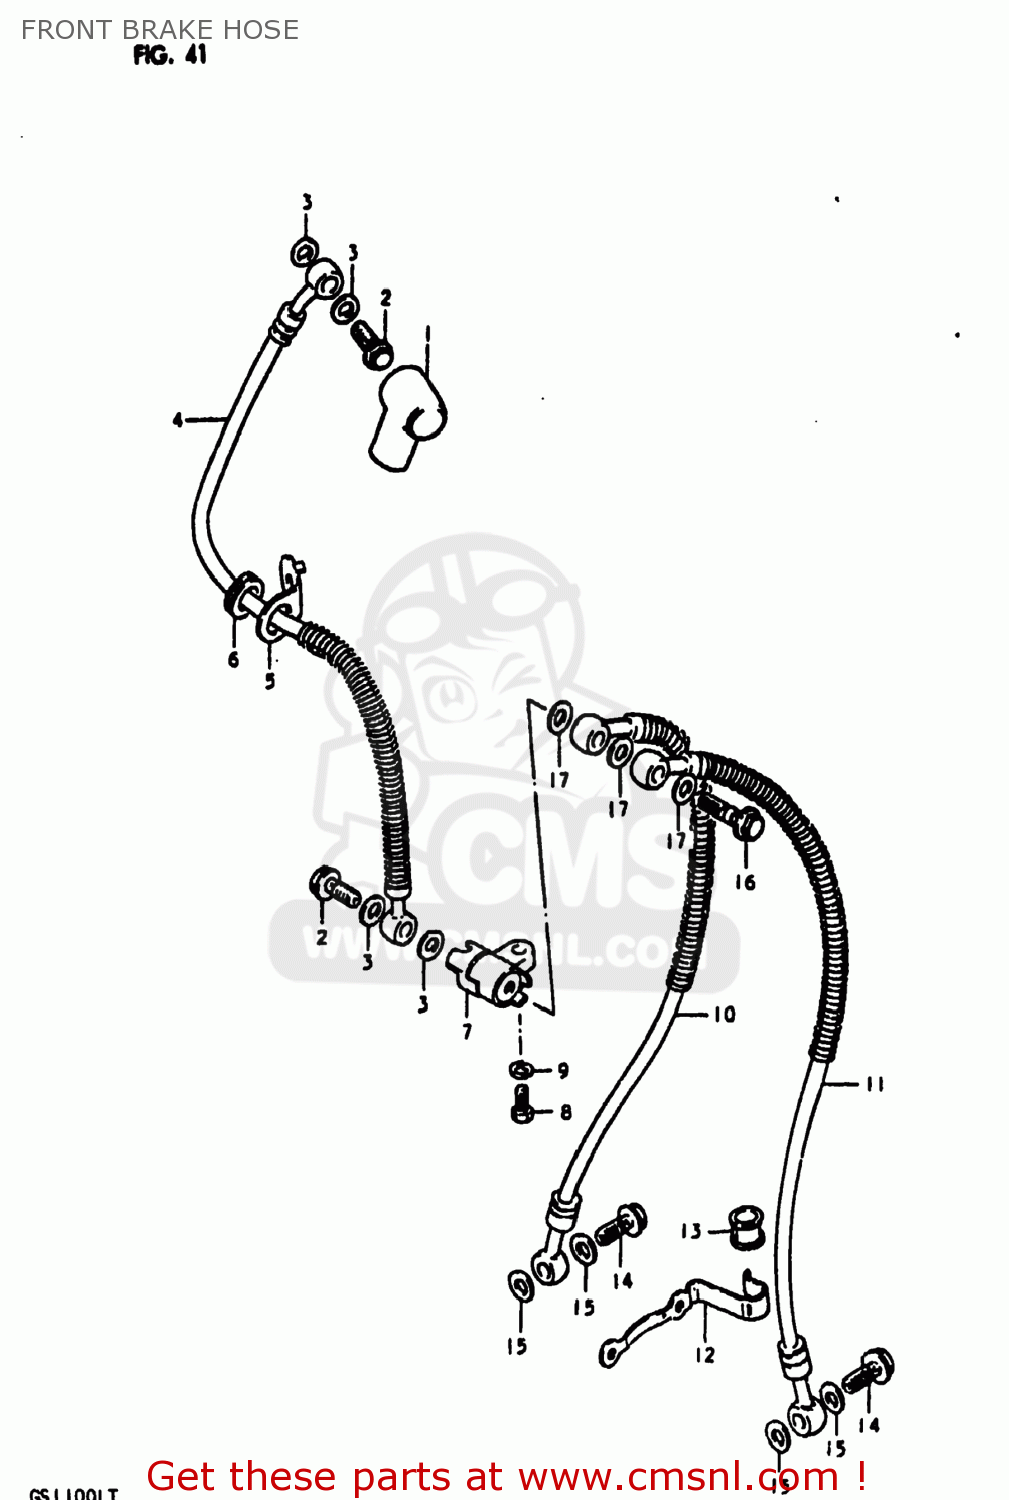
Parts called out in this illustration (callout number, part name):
1	BOOT,MASTER CYLINDER
2	BOLT,UNION
3	WASHER
4	HOSE,FRONT BRAKE NO.1
5	GUIDE,BRAKE HOSE
6	GROMMET
7	JOINT,BRAKE HOSE
8	BOLT
9	LOCK WASHER
10	HOSE,FR BRAKE NO.2,L
11	HOSE,FR BRAKE NO.2,L
12	GUIDE,BRAKE HOSE NO.2
13	BUSH,BRAKE HOSE GUIDE,NO.2
14	BOLT,UNION
15	WASHER
16	BOLT,UNION
17	WASHER
